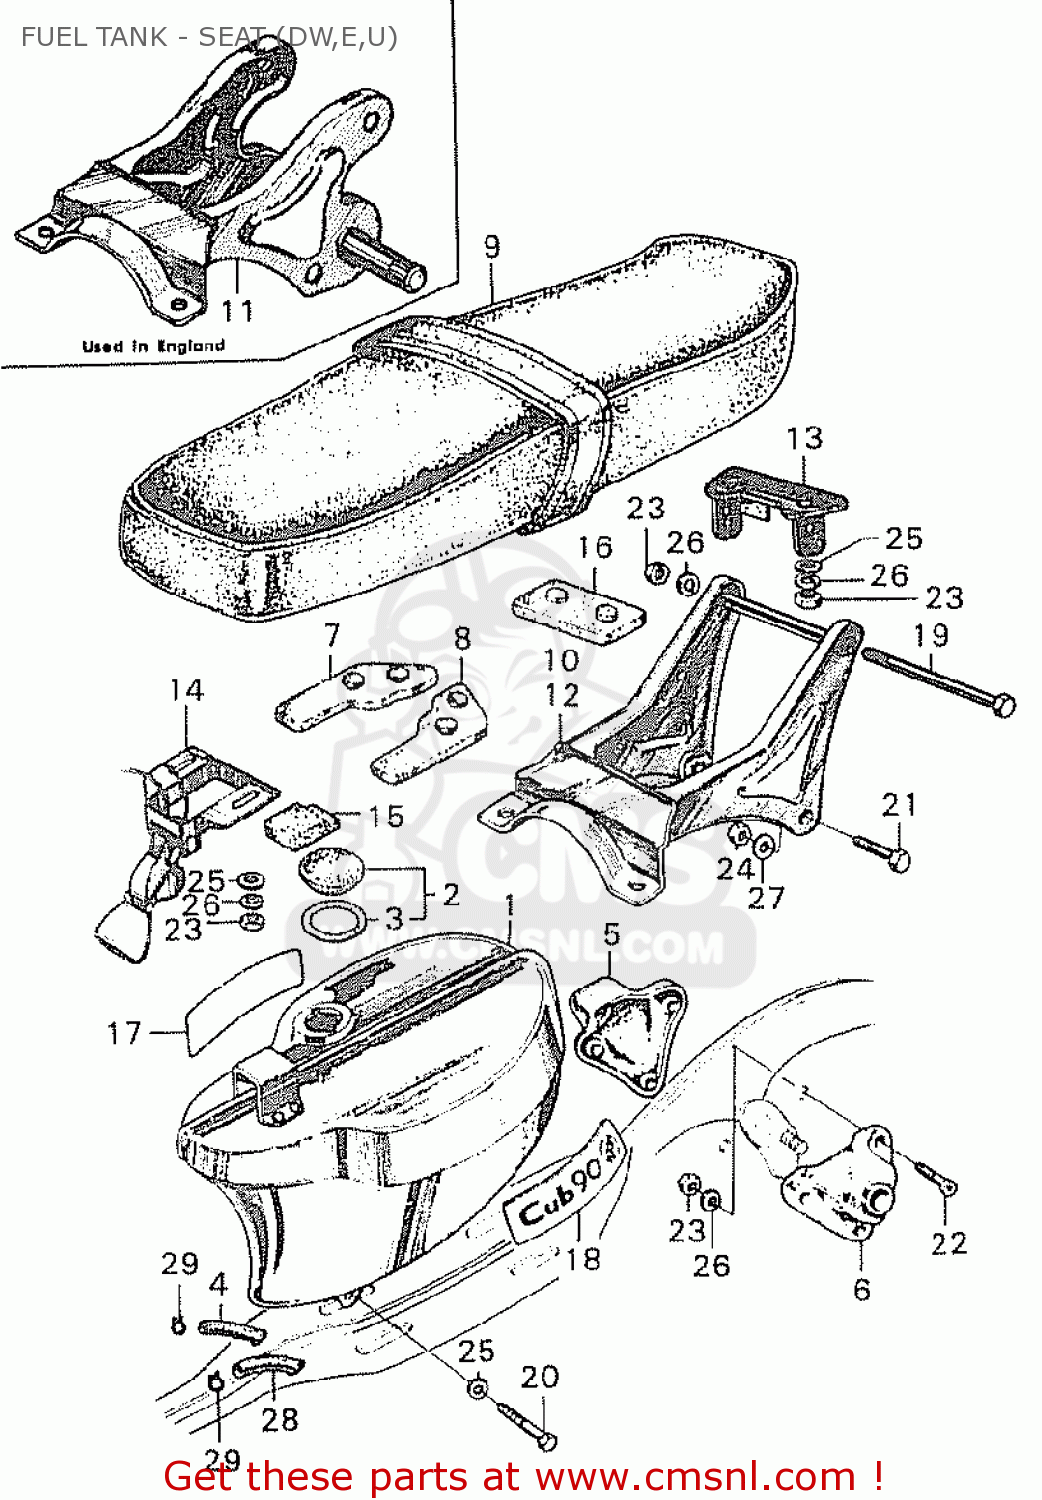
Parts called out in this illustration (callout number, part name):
1	TANK,FUEL
2	CAP FUELFILLER
3	PAKING,FUELFILLER
4	TUBE RESERVE
5	BRACKET CUSHION
6	BRACKET CUSHION
7	RUBBER, R. SEAT
8	RUBBER, L. SEAT
9	SEAT DUAL
11	BRACKET, TANDEM SEAT
13	BRACKET B SEAT
14	CATCH ASSY SEAT
15	STOPPER FRT SEAT
16	RUBBER REAR SEAT
17	EMBLEM RIGHT
18	EMBLEM LEFT
19	PIN SEAT HINGE
20	BOLT, HEX., 6X24
21	BOLT,HEX 8X16
22	SCREW,CROSS 6X16
23	NUT,HEX 6MM
24	NUT,HEX 8MM
25	WASHER,PLAIN, 6MM
26	WASHER,SPRING,6MM
27	SPG-WASHER 8MM
28	TUBE FUEL 50X450
29	CLIP,TUBE 5.0MM
